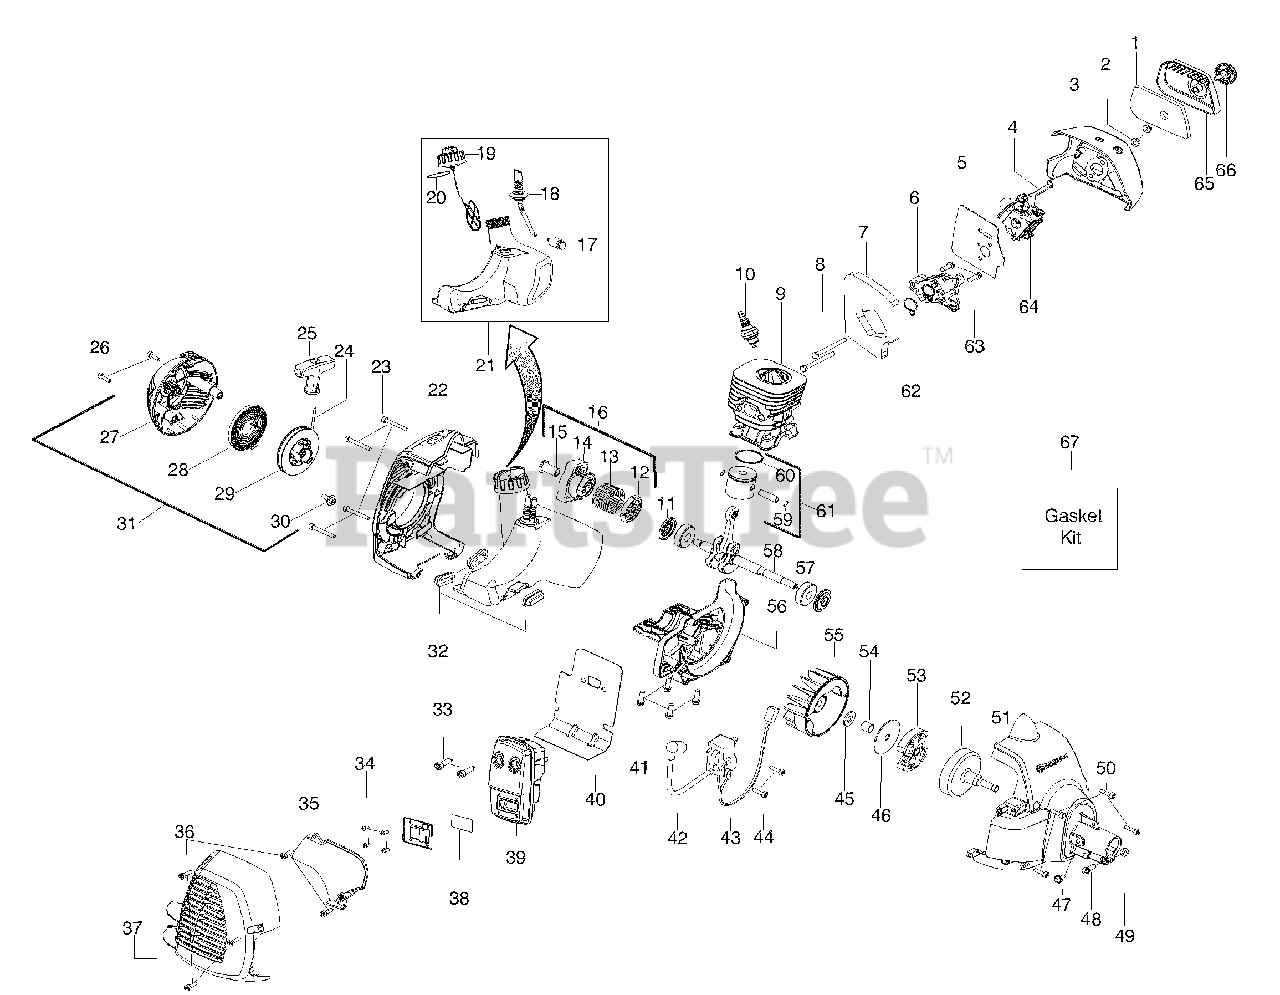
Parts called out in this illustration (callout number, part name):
2	Nut-Carb. Screw
3	Air Box
4	Lever - Choke
5	Kit-Carb. Gasket
6	Adaptor-Carb.
7	Kit-Gasket
9	Cylinder
10	Plug-Spark
11	Kit-Crankshaft seal
12	Washer - Starter
13	Spring - Starter Cup
14	Assy - Starter Cup
15	Coupling - Starter
16	Kit - Starter
17	Assy - Fuel Filter
18	Kit - Fuel Line
19	Assy-Cap w/ret.
20	O-ring - Fuel Cap
21	Assy-Fuel Tank
22	Shroud-Rear
25	Handle - Starter
27	Starter Hsg. w/eyelet
28	Kit-Starter Spring
29	Kit-Starter Pulley
31	Assy-Starter Hsg.
32	Isolator-Tank
33	Bolt-Muffler
35	Shield-Heat
37	Guard-Muffler
38	Kit-Spark Arrestor
39	Assy-Muffler
40	Gasket-Paper Metal
42	Module
43	Assy-Leadwire
46	Washer-Clutch
51	Assy-Fan Housing
52	Assy-Clutch Drum
53	Kit-Clutch Assy.
58	Kit-Crankshaft
59	Retainer-Piston Pin
60	Ring-Piston
61	Kit-Piston
62	Kit-Gasket
64	Kit-Carb.
65	Cover-Air Box
67	Kit-Gasket
